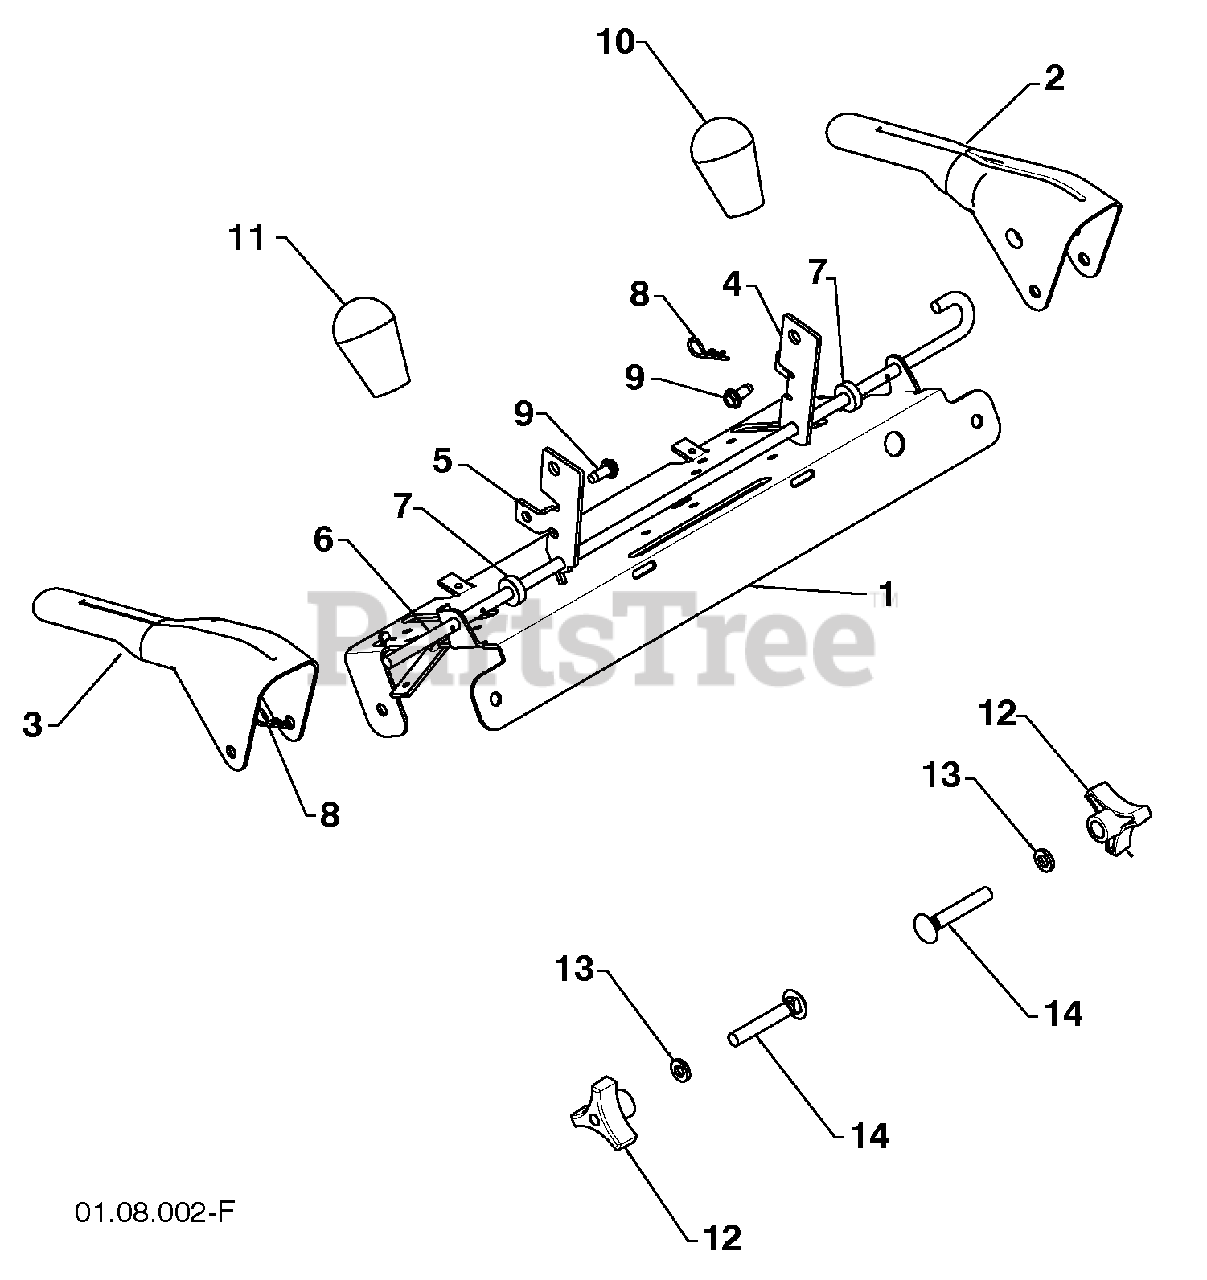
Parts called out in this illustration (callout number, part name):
1	CONTROL PANEL
2	CONTROL LEVER LH
3	CONTROL LEVER RH
4	TRACTION ROD ARM
5	IMPELLER ROD ARM
6	INTERLOCK BAIL
8	RETAINER
9	SCREW 1/4-20 X .62
10	KNOB BLACK
11	KNOB RED
12	HANDLE KNOB
13	WASHER 3/8
14	CARRIAGE BOLT 3/8-16 X 2.25
